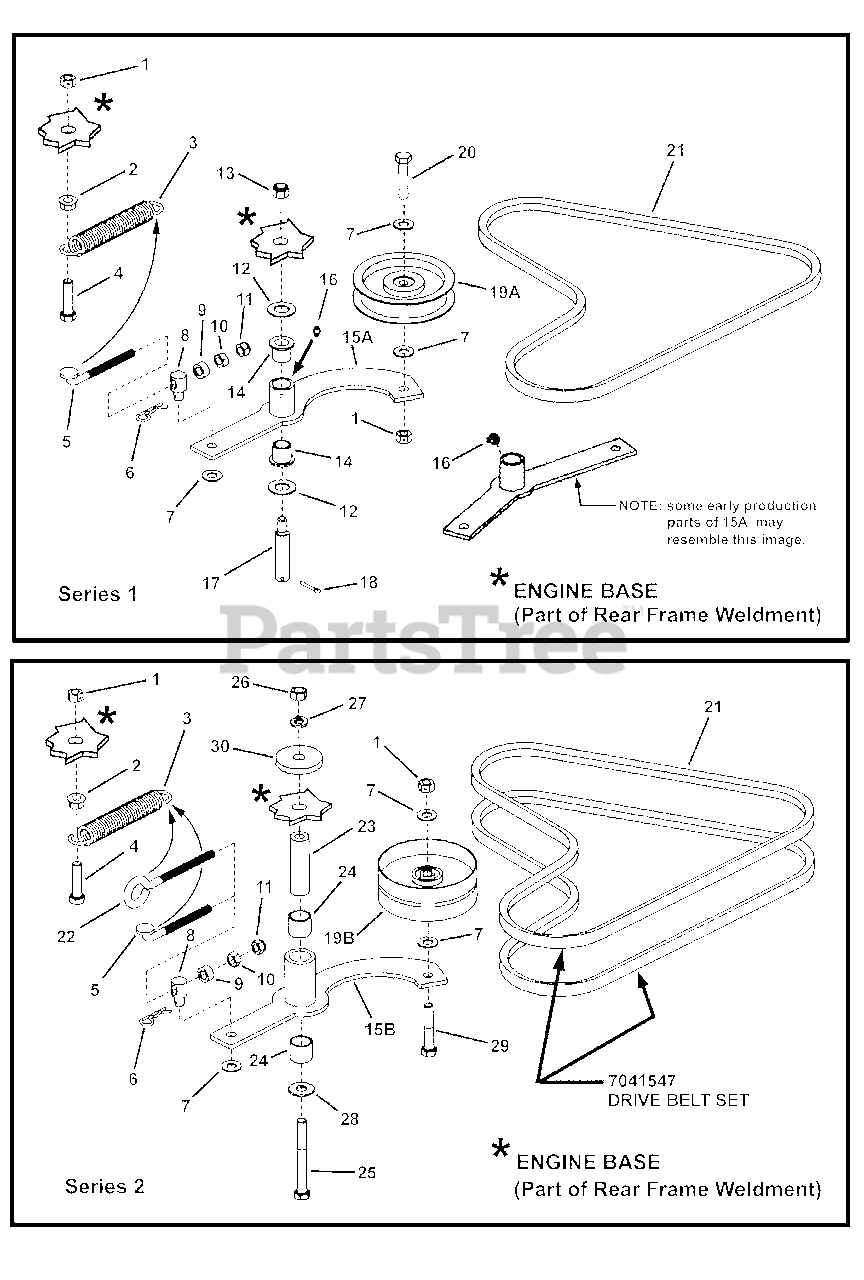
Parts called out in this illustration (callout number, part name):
1	NUT, 3/8-16 Hex Center Lock
2	NUT, 3/8-16 HEX SERRATED FLANGE
3	SPRING, Extension
4	SCREW, 3/8-16 x 1-1/2 Hex Head Cap, GR 5
5	ADJUSTER, Chain (5/16-18 Thread)
6	HAIR PIN, 3/32 x 1-1/2"
7	WASHER, 3/8" Flat SAE
8	SWIVEL, Adjustable
9	SPACER, .340 I.D. x .63 O.D. x .310 Thick
10	NUT, 5/16-18 Hex, GR 5 or B
11	NUT, 5/16-18 HEX NYLON LOCK
12	WASHER, 9/16" Flat
13	NUT, 3/8-24 Hex Nyloc
14	BUSHING, 9/16" I.D.
15A	WELDMENT, Idler Arm
15B	WELDMENT, Idler Arm
16	FITTING, 3/16" Straight Lube
17	PIN, Idler Arm (3/8-24 Thread)
18	PIN, 1/8 x 3/4" Cotter
19A	PULLEY, Flat Idler 4.12" (Backside Idler)
19B	PULLEY, 4" O.D. x .391 I.D. x 1.25 Backside Idler
20	SCREW, 3/8-16 x 1-3/4" Hex Head Cap, GR 5
21	BELT, Hydro Drive (HA Section, 47.5 Effective Length)
21	SET, Matched Traction Drive Belts
22	EYEBOLT, 5/16-18
23	BOSS, IDLER,YELLOW GV3036304
24	BUSHING, SLEEVE, 3/4 ID, GV3031224
25	BOLT, 3/8-16 x 3-1/2" Hex Head, GR 5
26	NUT, 3/8-16 Hex, GR 5 or B
27	WASHER, 3/8" Split Lock
28	WASHER, 3/8" USS
29	SCREW, 3/8-16 x 2-1/4" Hex Head Cap, GR 5
30	WASHER, .468 x 1.85 x .25
